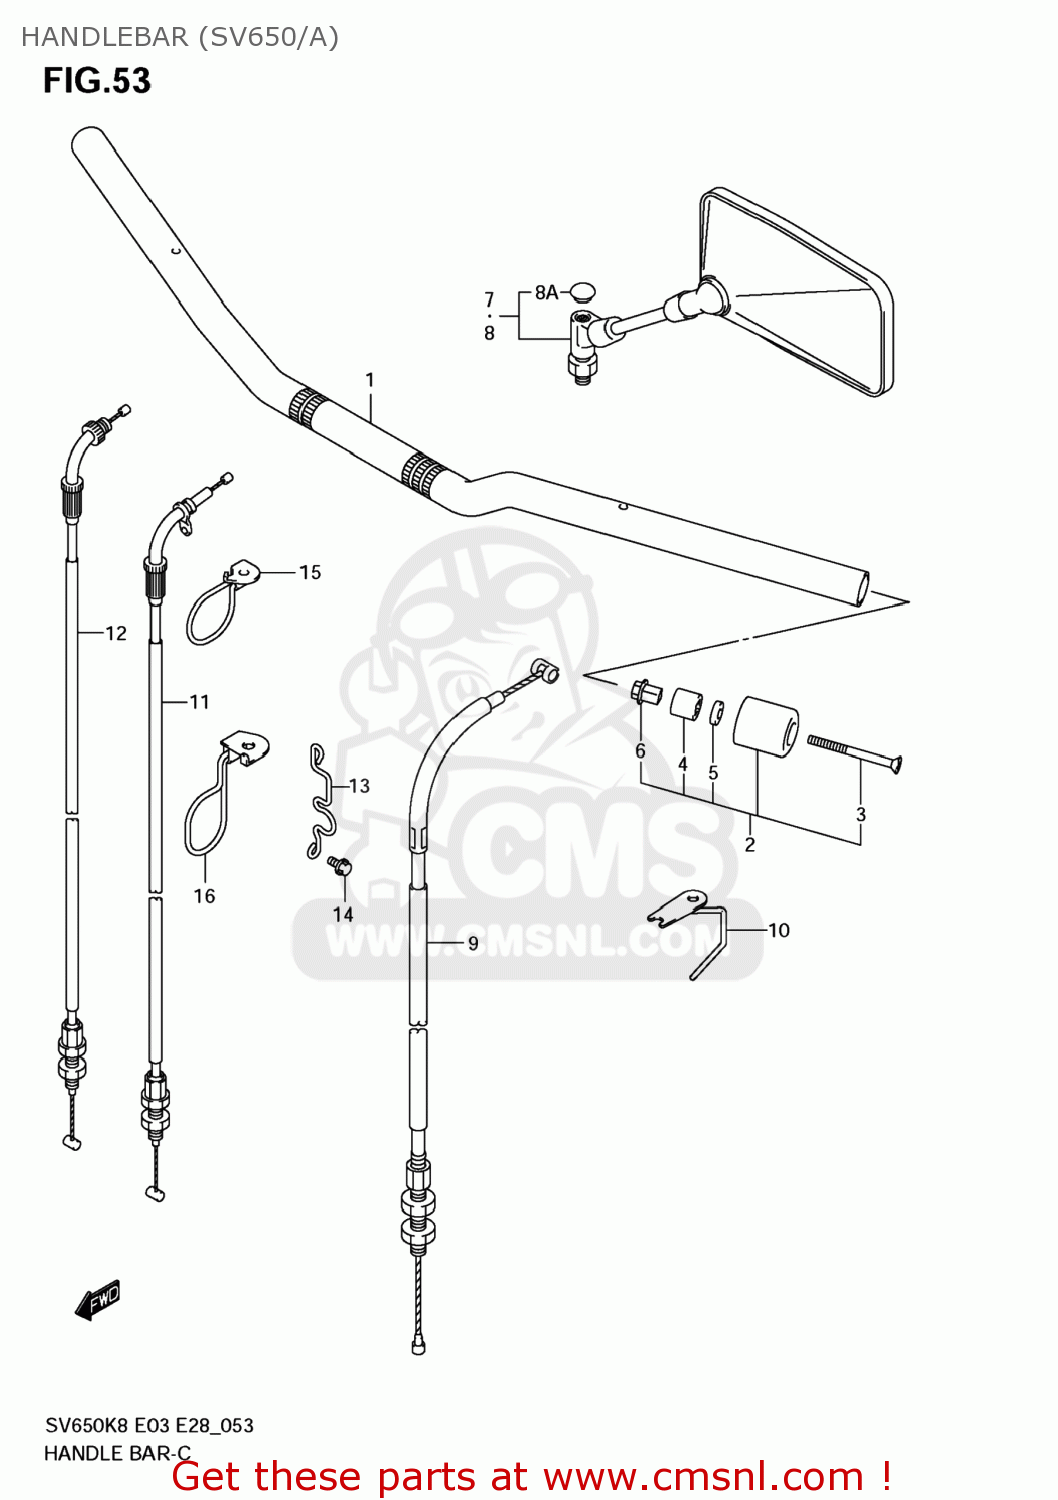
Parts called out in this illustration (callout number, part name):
1	HANDLEBAR
2	BALANCER SET,HANDLEBAR
3	SCREW
4	EXPANDER,HANDLE BALANCER
5	WASHER(6.5X16X4)
6	NUT,HANDLE BALANCER
7	MIRROR ASSY,RR VIEW,R
8	MIRROR ASSY,RR VIEW,L
8A	CAP
9	CABLE ASSY,CLUTCH
10	GUIDE,CLUTCH CABLE
11	CABLE ASSY,THROTTLE NO.1
12	CABLE ASSY,THROTTLE NO.2
13	GUIDE,CABLE L
14	BOLT
15	GUIDE,THROTTLE CABLE
16	GUIDE,THROTTLE CABLE NO.2
